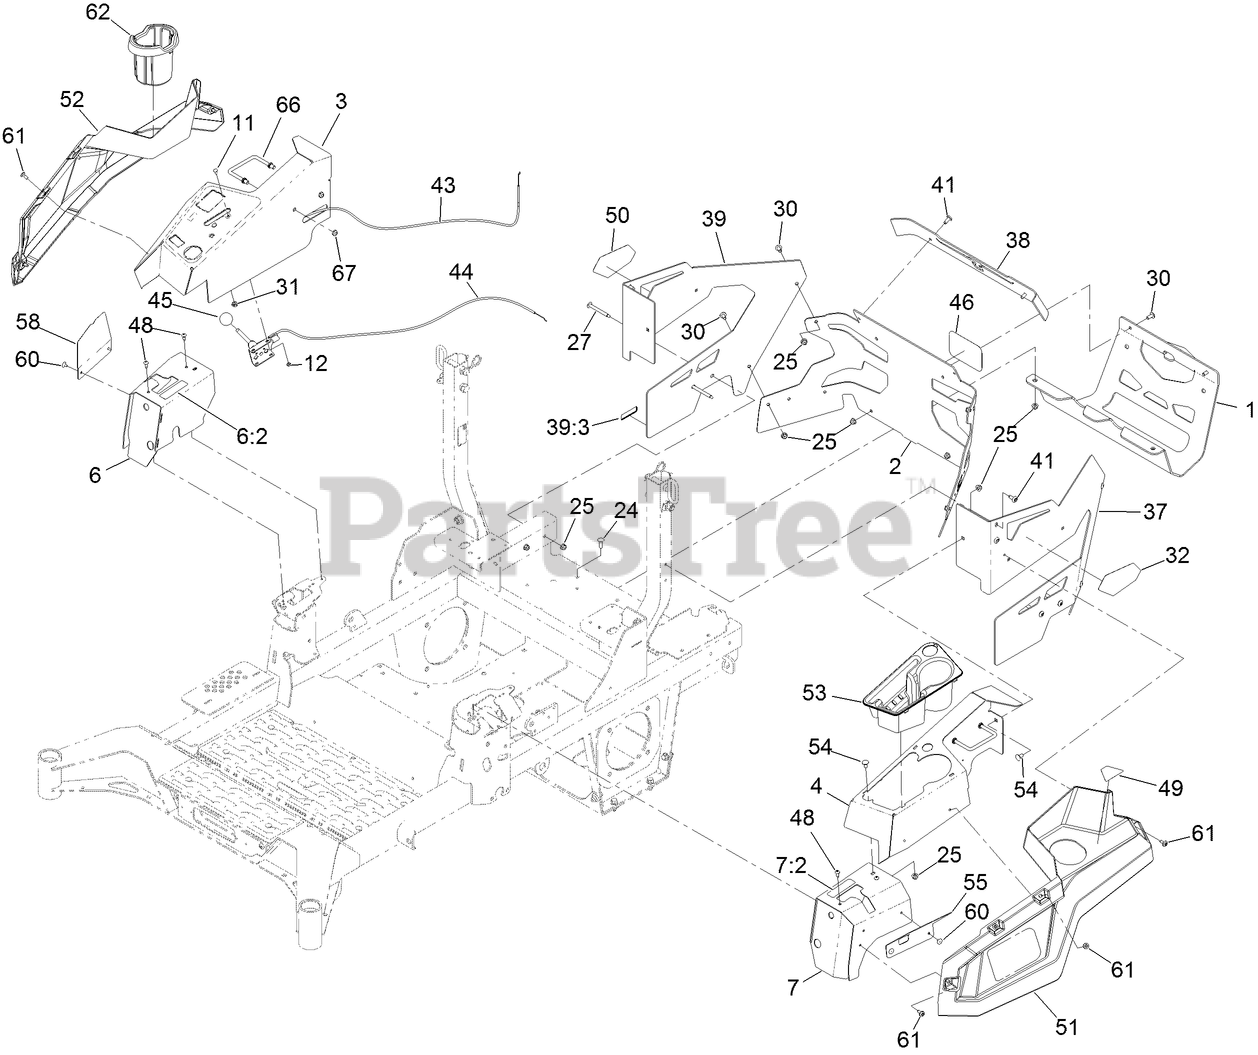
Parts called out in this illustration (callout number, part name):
1	GUARD-MUFFLER [BLACK]
2	REAR GUARD ASM
3	CONSOLE-RH
4	CONSOLE-LH
6	RH COVER ASM
6:2	DECAL-CONTROL, MOTION
7	LH COVER ASM
7:2	DECAL-CONTROL, MOTION
11	BOLT-CARR
12	NUT-LOCK, NI
24	SCREW-CARR
25	NUT-HF, NI
27	SCREW-TORX
30	SCREW-TORX
31	NUT-HJ
32	DECAL - 4000 SERIES, LH
37	GUARD-REAR, LH
38	GUARD-REAR, TOP
39	RH REAR GUARD ASM
39:3	DECAL-ARRESTOR, SPARK
43	CABLE-CONTROL, CHOKE
44	CABLE-CONTROL, THROTTLE
45	KNOB-BALL
48	SCREW-TPH THD FORM
49	DECAL-FILL, FUEL
50	DECAL-4000 SERIES, RH
51	SIDE POD, LH
52	SIDE POD, RH
53	CUP HOLDER
54	SCREW-CARR
55	PLATE-COVER, LH FRONT
58	PLATE-COVER, RH FRONT
60	RIVET-POP
61	SCREW-SHOULDER
62	CUPHOLDER-RH
66	ROD-SUPPORT, POD
